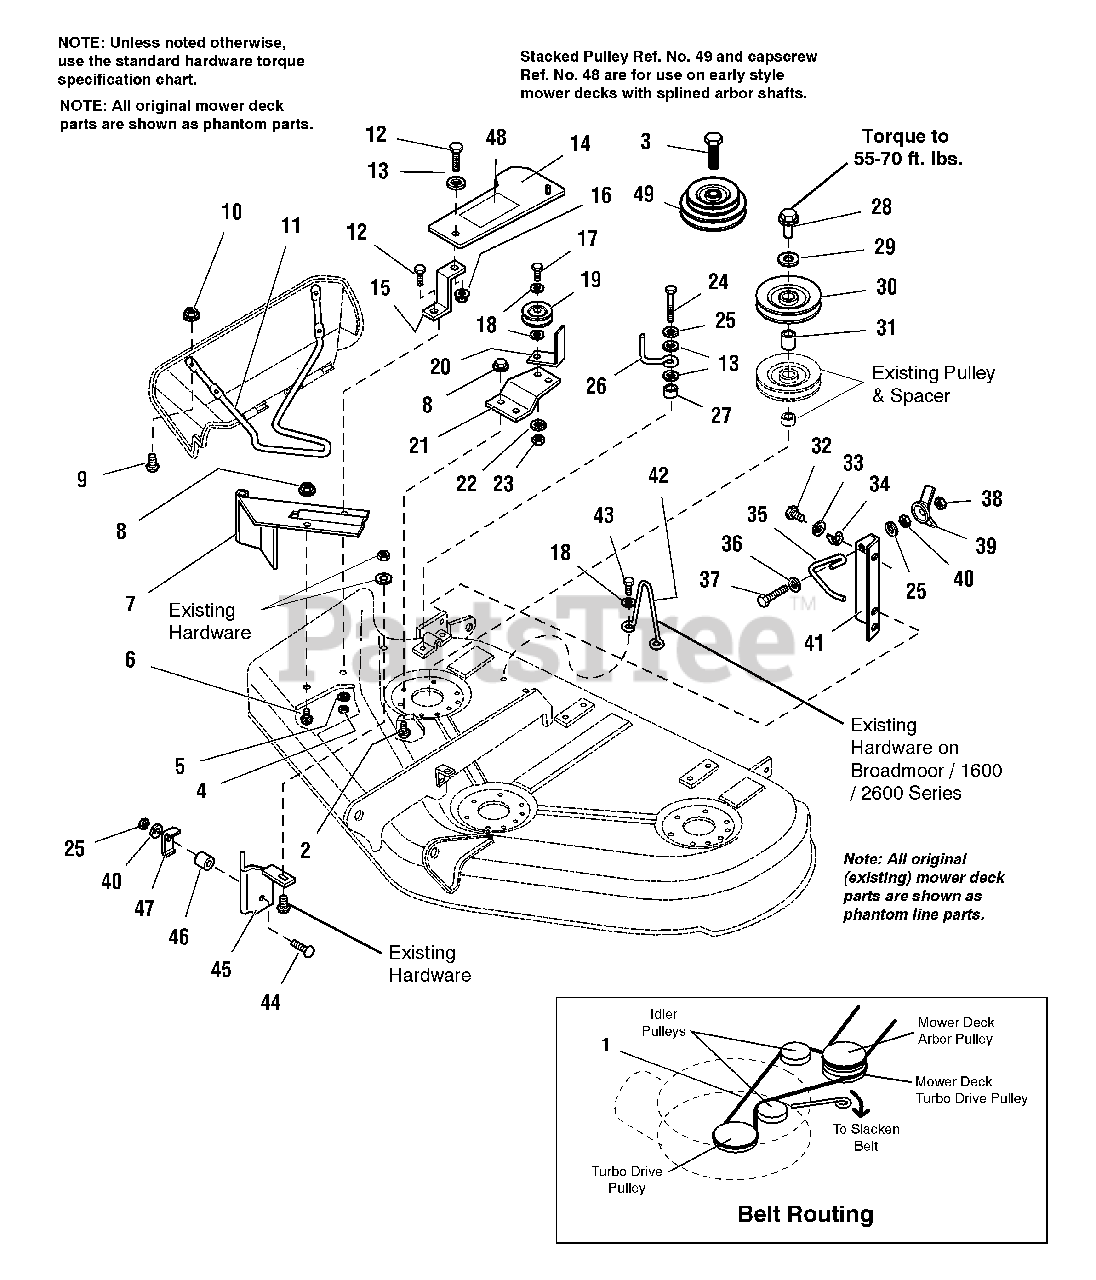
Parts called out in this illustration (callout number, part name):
2	CAPSCREW, Hex Hd, 5/16-18 x 7/8
3	CAPSCREW, 7/16-14 x 2
4	NUT, Hex, Whizlock, 5/16-18
5	WASHER, 5/16
6	CARRIAGE BOLT, 5/16-18 x 3/4
7	PIVOT ASSEMBLY
8	NUT, Hex Whizlock, 5/16-18
9	SCREW, Truss Hd, #10-24 x 3/4
10	NUT, Hex, Nylon Lock, #10-24
11	ROD, Deflector
12	CAPSCREW, Hex Hd, 5/16-18 x 1
13	WASHER, 5/16
14	COVER, Belt
15	SUPPORT, Belt Cover
16	NUT, Hex 5/16-18
17	CAPSCREW, Hex Hd 3/8-16 x 1-1/2
18	WASHER, Flat, 3/8
19	PULLEY ASSEMBLY, Idler
20	LATCH, Belt Cover
21	BRACKET, Idler
22	LOCKWASHER, 3/8
23	NUT, Hex, 3/8-16
24	CAPSCREW, HEX HD, 5/16-18 X 1-1/2
25	LOCKWASHER, 5/16
28	NUT, Sleeve
29	WASHER, Belleville
31	HUB, Double Pulley
32	CAPSCREW, Hex Hd, 1/4-20 x 1/2
33	WASHER, 1/4
34	BELT STOP, (Height Indicator)
35	LATCH, Spring
36	WASHER, 5/16
37	CAPSCREW, Hex Hd, 5/16-18
38	NUT, Hex Lock, 5/16-18
39	NUT, Wing, 5/16
40	NUT, Hex, 5/16-18
41	BRACKET, Anchor
42	UPSTOP, Wire
43	CAPSCREW, Hex Washer Hd, Taptite, 5/16
44	CARRIAGE BOLT, 5/16-18
45	BRACKET ASSEMBLY, Cutoff
48	DECAL, Warning
49	PULLEY, Double
